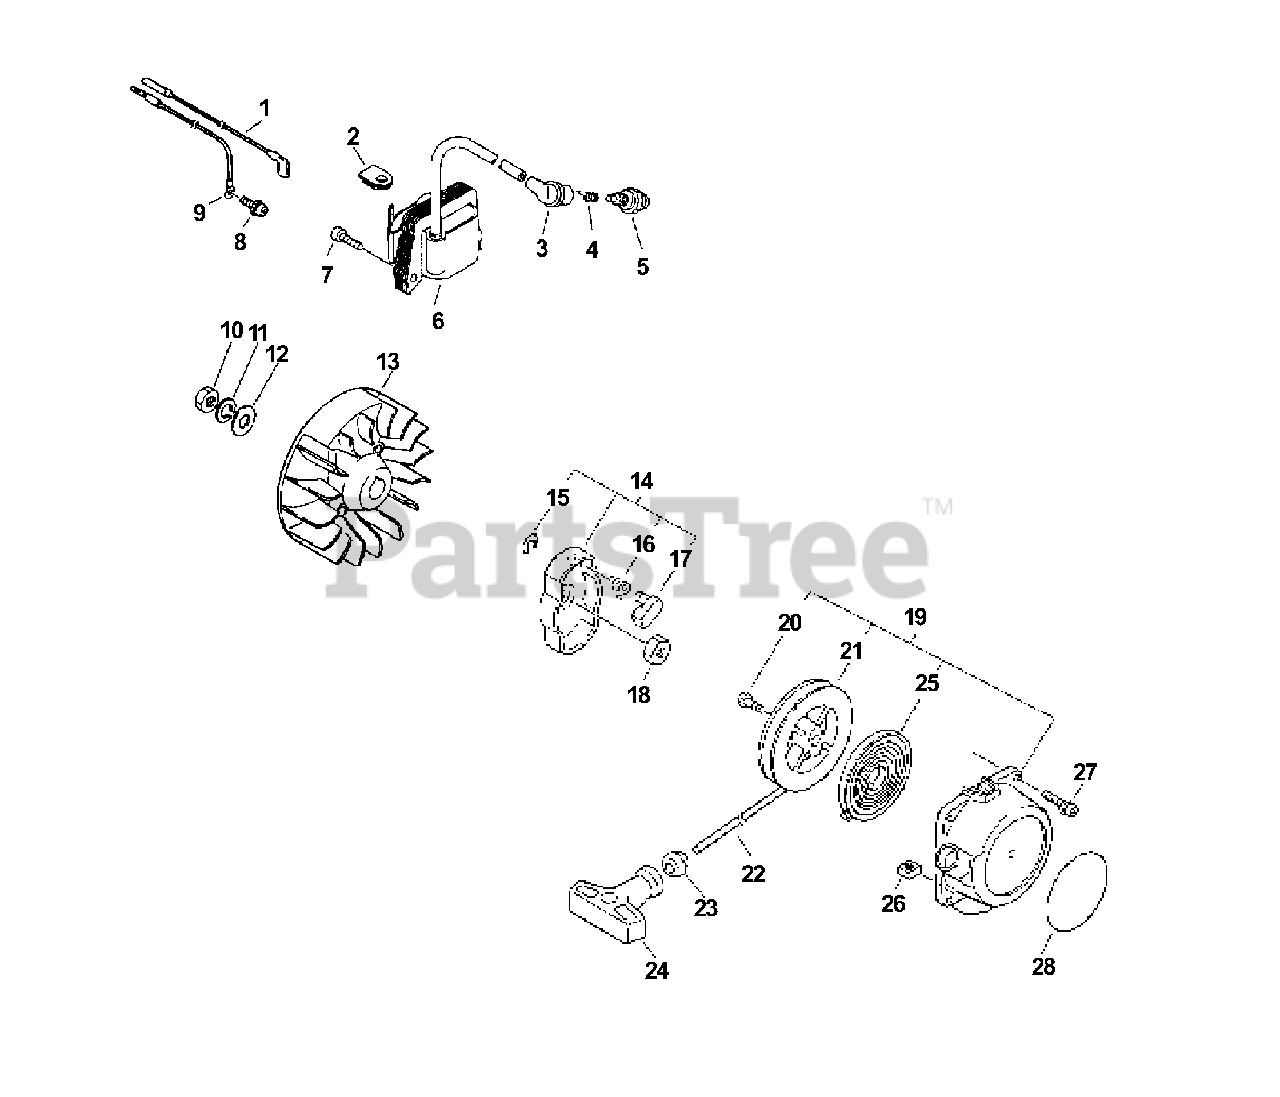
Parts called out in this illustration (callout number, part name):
1	LEAD - IGNITION
3	CAP, SPARK PLUG
4	TERMINAL, SPARK PLUG CAP
5	SPARK PLUG -- BPM-7Y
5	SPARK PLUG -- BPMR-7A
6	COIL, IGNITION
7	SCREW - 5X20
8	SCREW - 5X10
9	LEAD - GROUND
11	LOCKWASHER - 8
12	WASHER - 8
13	FLYWHEEL
14	STARTER PAWL ASSY
15	RING, RETAINING - 4
16	SPRING, RETURN
17	PAWL, STARTER
19	STARTER ASSY
21	REEL, ROPE
22	ROPE, STARTER
23	GUIDE, ROPE
24	GRIP, STARTER
25	SPRING, REWIND
26	NUT - 5 -- SQUARE
27	SCREW - 4X14
28	LABEL - ECHO
